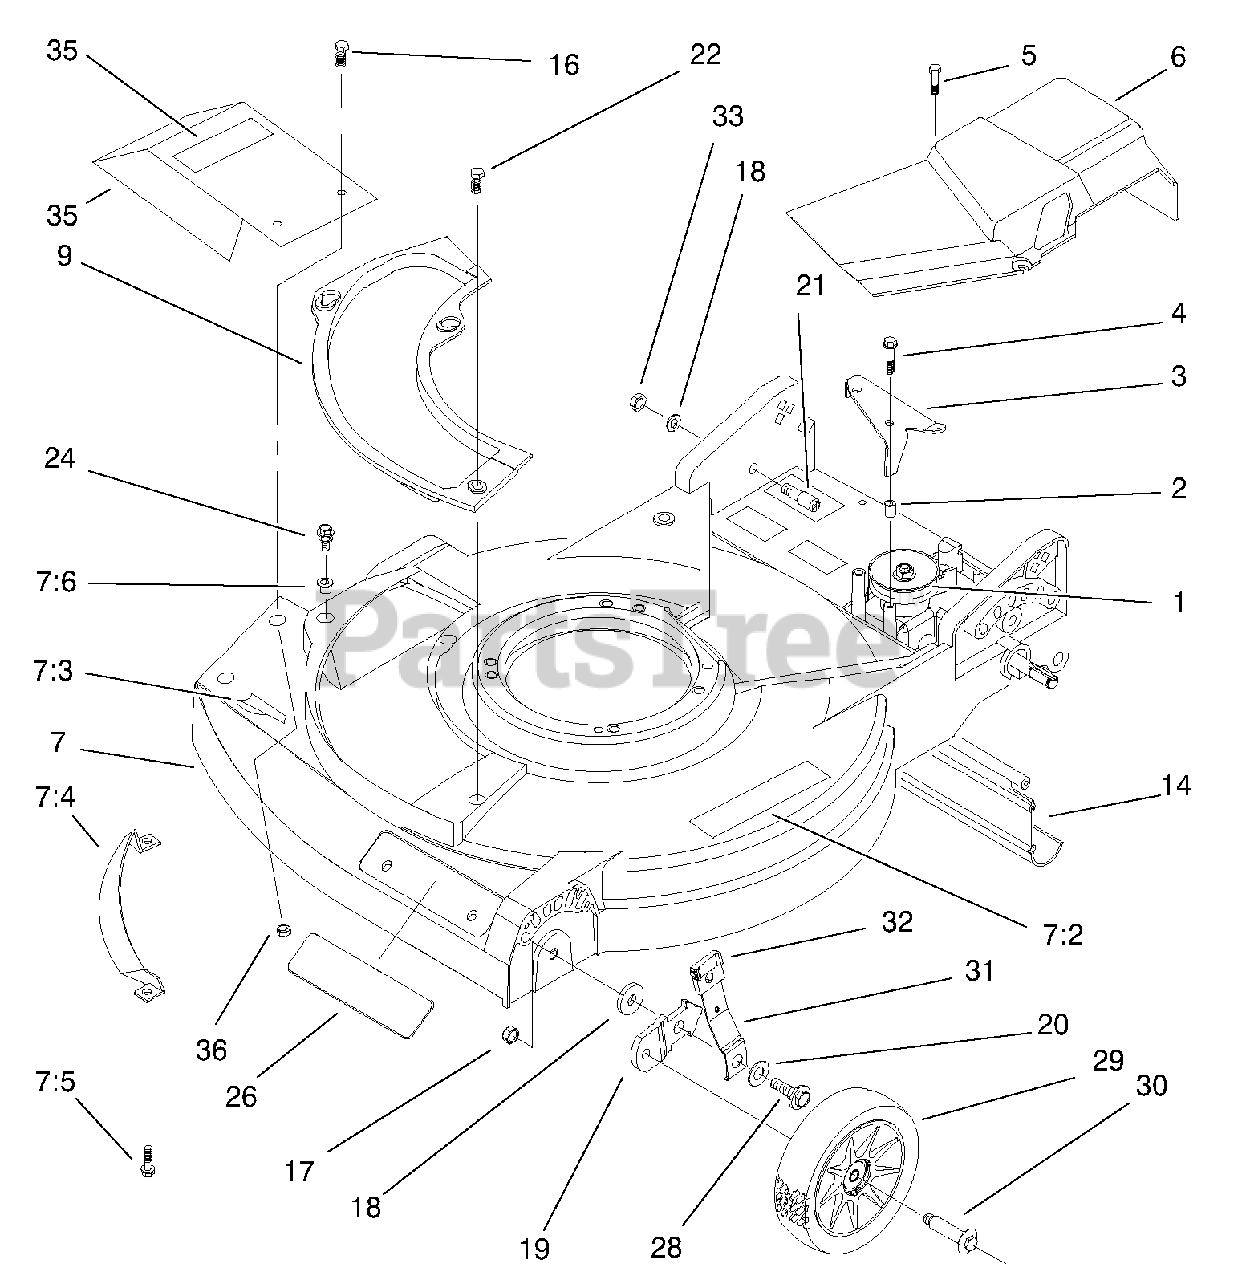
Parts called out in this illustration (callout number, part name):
1	Gear Case ASM
3	Bracket-Actuator
4	Screw-HWH
6	Cover-Drive
7	Housing ASM
7:2	Decal-Bag Door
7:3	Decal-Danger
7:4	Toe Bar
7:5	Screw & Washer ASM
7:6	Grommet-Plastic
9	Plate-Chute Opening
14	Shield-Trailing
16	Screw-Machine
17	Nut-Lock, NI
18	Washer-Bolt, Wheel
19	Bracket-Wheel Height Adj.
20	Washer-Belleville
21	Screw-Torx, Machine
22	Screw-Taptite
24	Screw-Sems
26	Decal-Deck,Sp
28	Bolt,Shoulder, Black
29	Wheel/Tire ASM
31	Front Spring Arm ASM
32	Knob-Height Adj. Lever
35	Guard Plate
35:1	Decal-Deflector
36	Nut-Lock
